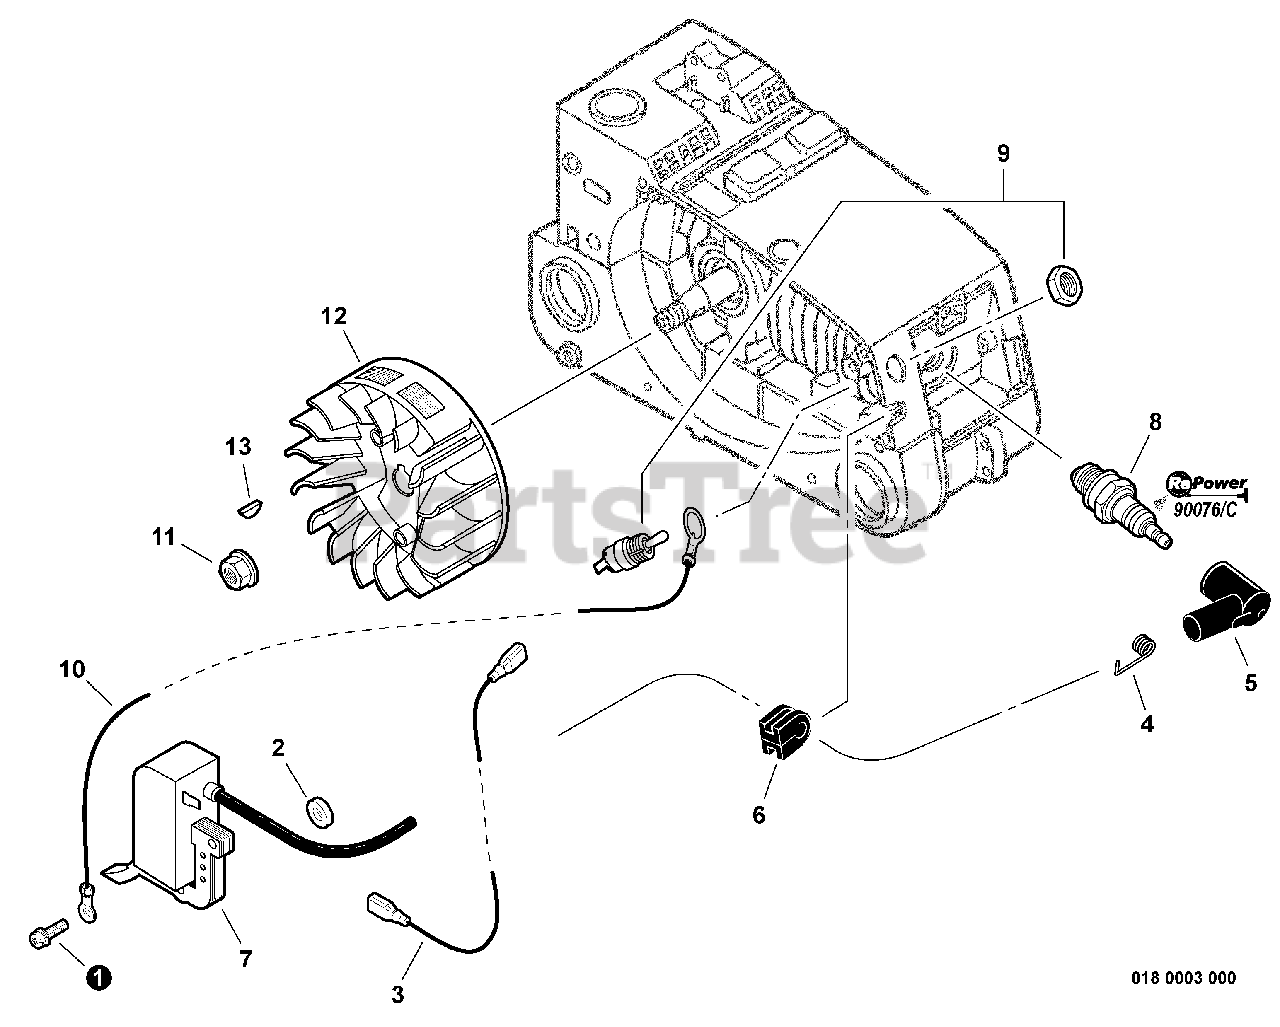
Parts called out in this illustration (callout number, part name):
1	SCREW 5×22
2	WASHER 5.2×12×3
3	LEAD - IGNITION L= 95
4	TERMINAL, SPARK PLUG
5	CAP, SPARK PLUG
7	COIL, IGNITION
8	SPARK PLUG - BPM8Y
8	SPARK PLUG - BPMR8Y
9	SWITCH, ON-OFF
10	LEAD - GROUND L= 100
11	NUT, FLANGE M8
12	FLYWHEEL
13	KEY, WOODRUFF
14	TUNE-UP KIT
